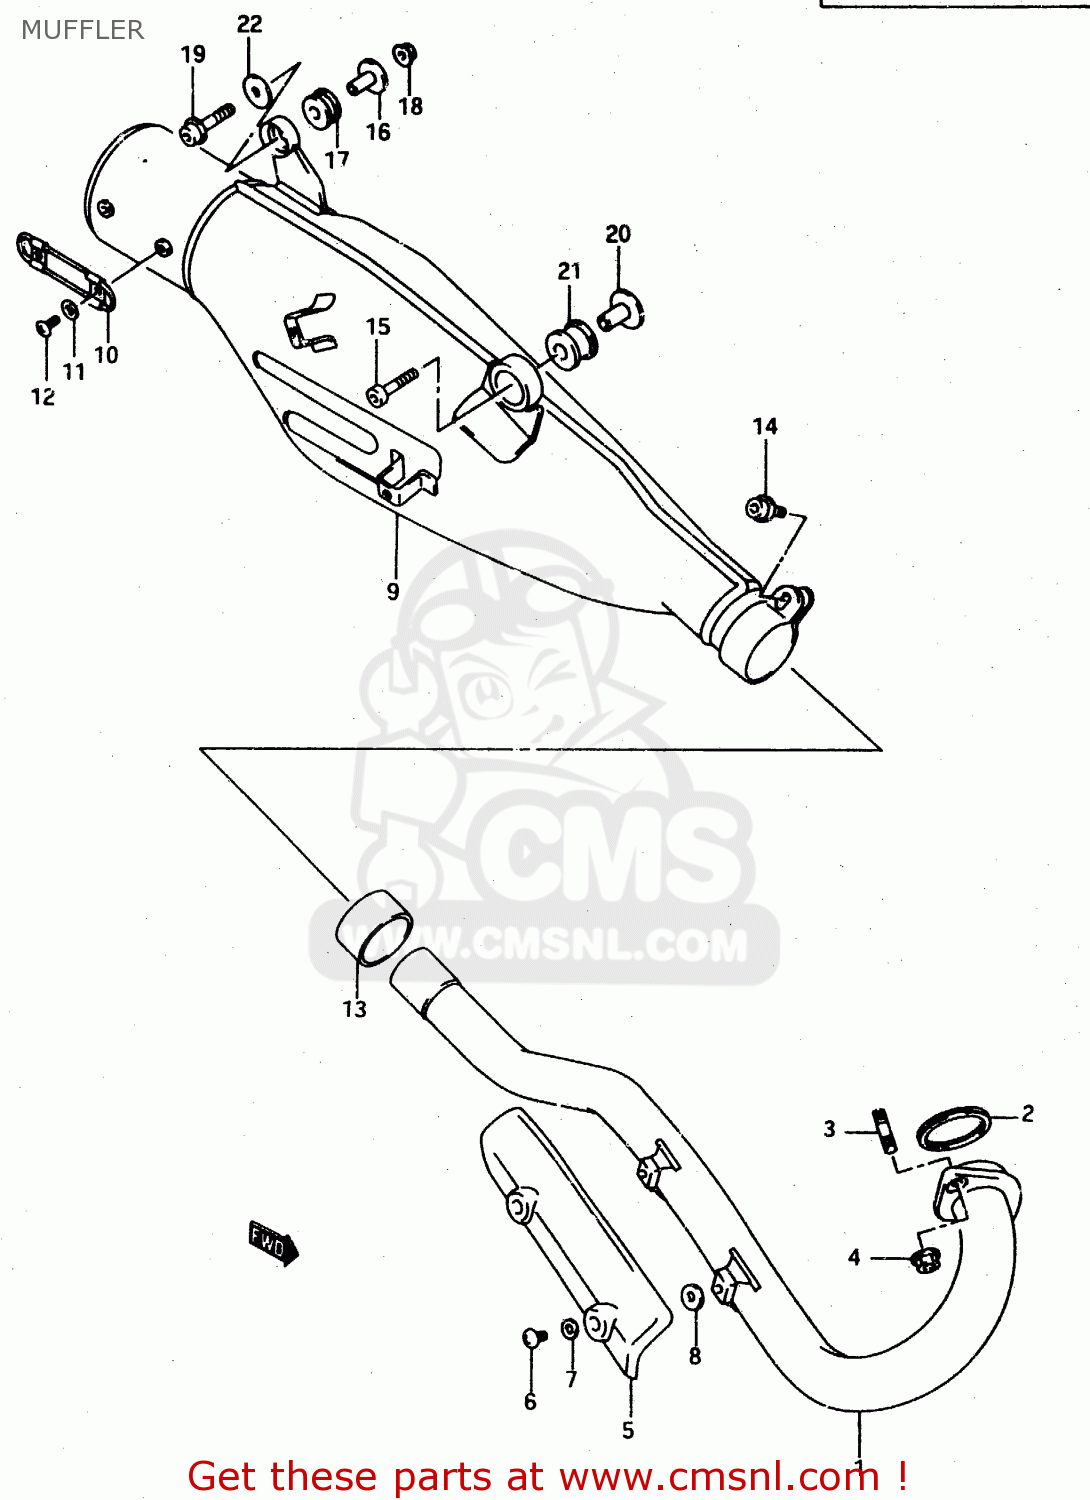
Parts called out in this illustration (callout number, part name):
1	PIPE,EXHAUST
2	GASKET,EXHAUST PIPE (NAS)
3	BOLT,STUD(8X20)
4	NUT
5	COVER,EXHAUST PIPE
6	SCREW(6X10)
7	WASHER(6.5X13X1.0)
8	GASKET(6X16X1.4) (NAS)
9	BODY, MUFFLER
10	COVER,MUFFLER
11	WASHER
12	SCREW(6X10)
13	CONNECTOR,MUFFLER
14	BOLT
15	BOLT(8X40)
16	SPACER(8.6X12X17.5)
17	CUSHION
18	NUT
19	BOLT
20	SPACER(8.6X12X24.2)
21	CUSHION
22	WASHER (8.5X20X1.6)
